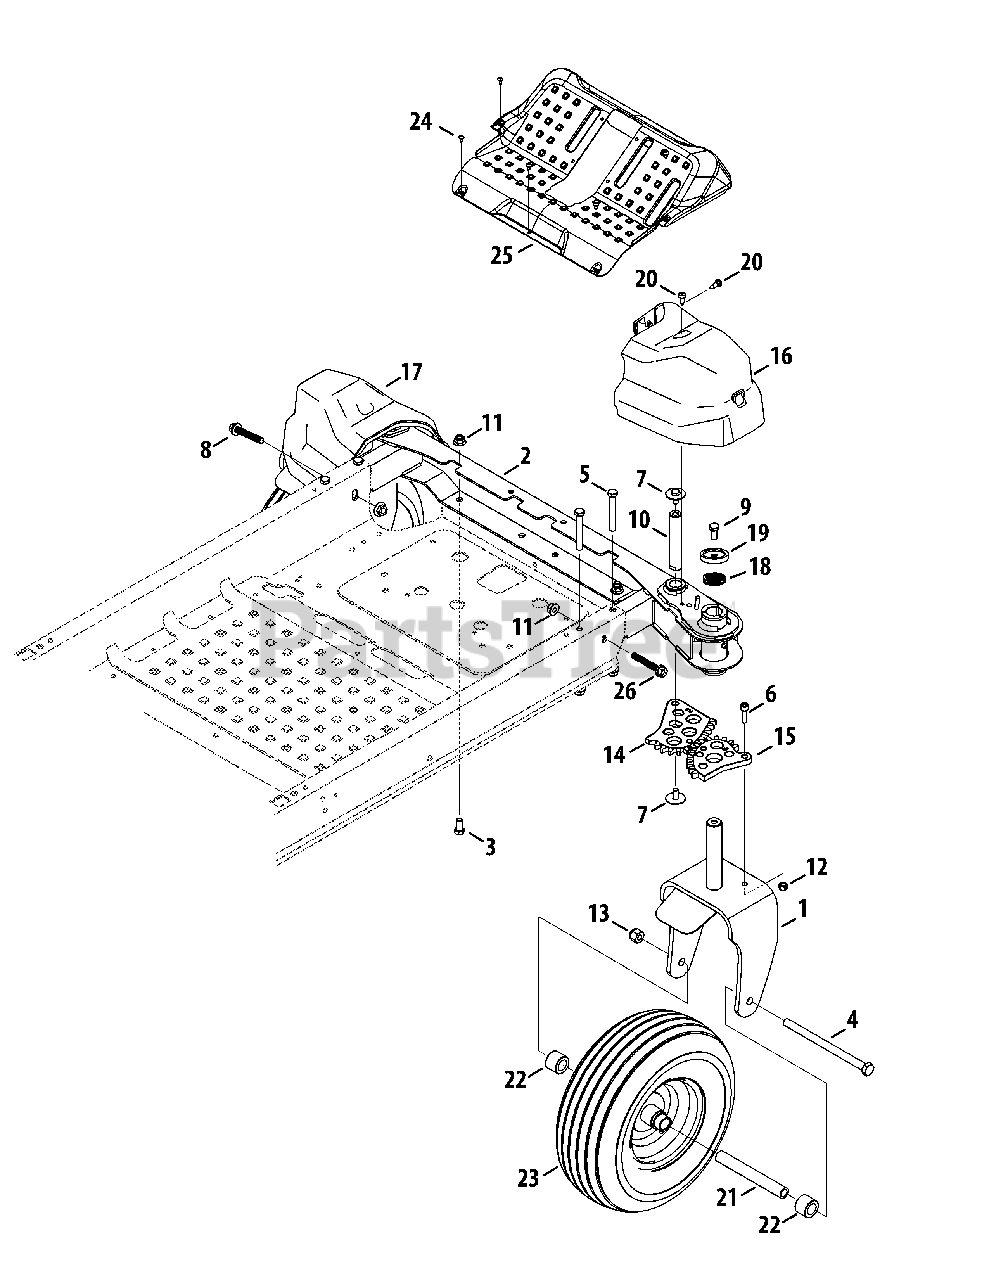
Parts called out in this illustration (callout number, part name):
1	Caster Wheel Bracket
2	Front Axle
3	Hex Cap Screw, 3/8-16 x .75
4	Bolt, 1/2-20 x 7.25
5	Screw, 3/8-16 x 2.75
6	Socket Head Screw, 5/16-18 x 1.00
7	Hex Cap Screw, 5/16-18 x .75
8	Hex Flange Screw, 3/8-16 x 2.25
9	Hex Screw, 3/8-16 x .75
10	Pivot Gear Steering Shaft
11	Flange Lock Nut, 3/8-16
12	Hex Lock Nut, 5/16-18
13	Hex Lock Nut, 1/2-20
14	12-Tooth Variable Gear
15	13-Tooth Variable Spur Gear
16	Axle Cover, RH
17	Axle Cover, LH
18	Wave Washer, 1.25 x 1.00 x .300
19	Shoulder Spacer, 1.75 x .180
20	Shoulder Screw, 1/4-20
21	Spacer, .51 ID x .75 OD x 5.825
22	Hub, .76 x 1.23 x .92 LG
23	Wheel Assembly, 13 x 5-6 CARLISLE
23	Wheel Assembly, 13 x 5-6, DELI TIRE
24	Self Tapping Screw, 1/4-20 x .50
25	Floor Board
26	Hex Flange Screw, 3/8-16 x 2.00
